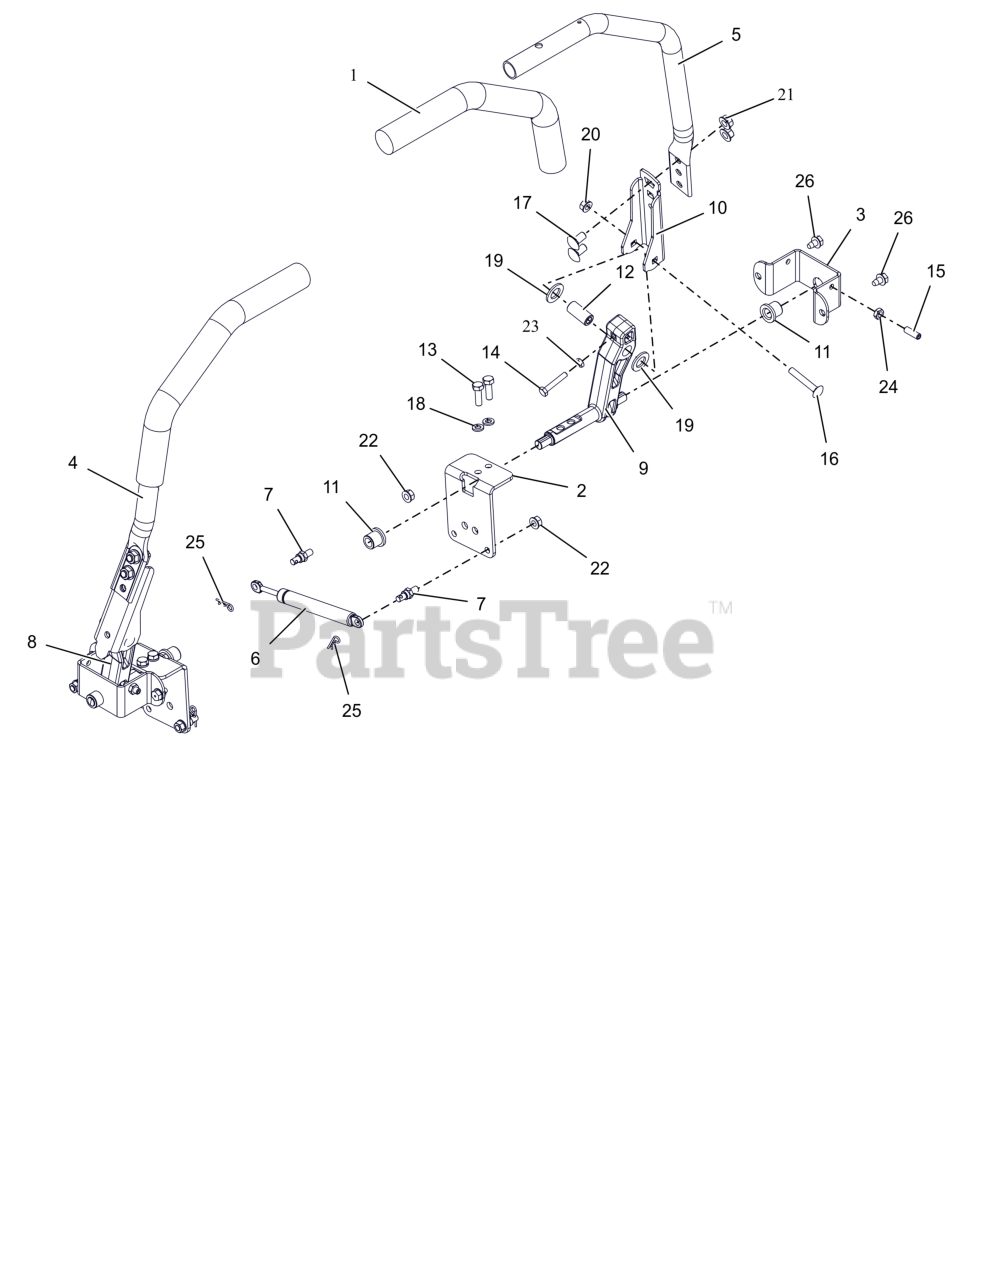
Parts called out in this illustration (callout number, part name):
1	GRIP, HANDLEBAR
2	BRKT, STEEERING
3	BRKT, STEERING
4	HANDLE, STEERING - RH (RED)
5	HANDLE, STEERING (RED)
6	DAMPER, STRAIGHT MOUNT
7	COUPLER, DAMPER MOUNT
8	STEERING, RH LWR CAST ARM
9	STEERING, LH LWR CAST ARM
10	ARM, CONTROL -UPPER (RED)
11	BHSG-FLG .500X.750X.750X.125
12	BSHG-SLV .342 X .627 X 1.331
13	BLT, HEX .31-18X1.00 G8 ZCC
14	BLT, HEX 0.25-20X1.5F GR5 ZCC
15	SCR-SET, .312-18X1.000
16	BLT, RHSSN .31-18X2.00 G5 ZCC
17	BTL,RHSSN .375-16 X 0.75 G5 FPB
18	WSHR,LK-REG .312X.078 ZCC
19	WSHR, FRICTION
20	NUT,LK-CTR-FLG .31-18 GF ZCC
21	NUT-LK-CTR-FLG .375-16 GF ZCC
22	NUT-LK-TOP-FLG .312-18 GF ZCC
23	NUT-JAM .250-20 G2 ZCC
24	NUT-JAM .312-18 G2 ZCC
25	PIN, HAIR #213 .08X1.19 ZCC
26	SCR,TAP .312-18X.50 HWH TR ZCC
